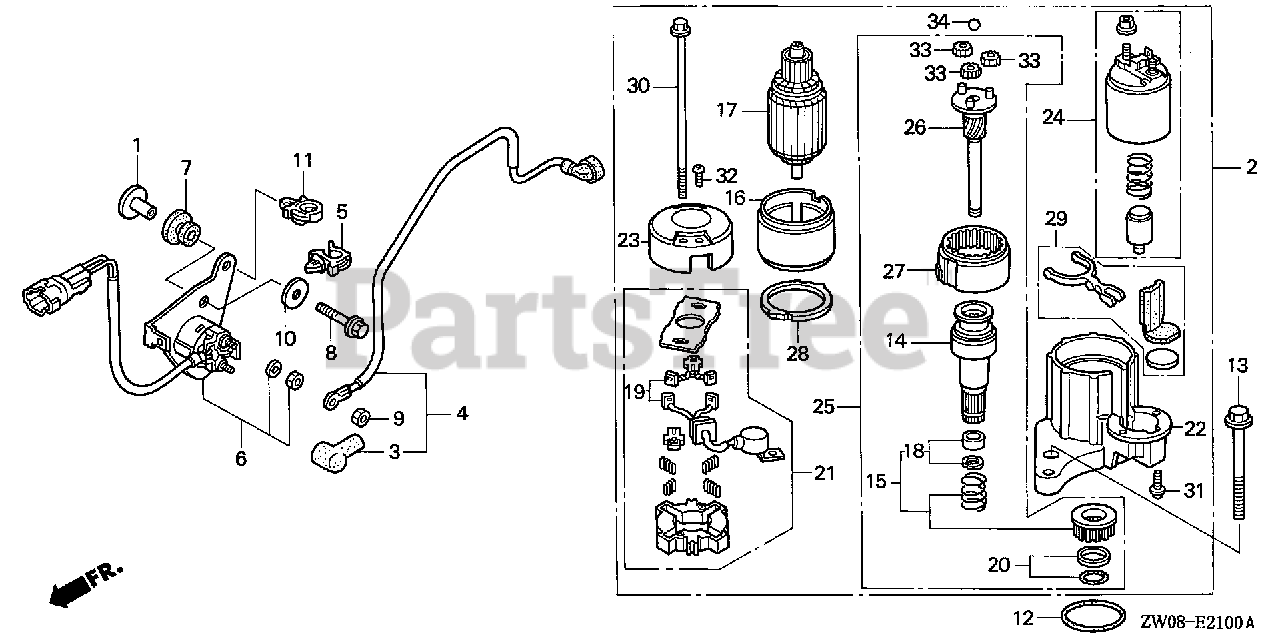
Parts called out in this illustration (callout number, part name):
1	COLLAR, FUEL TANK MOUNTING
2	MOTOR ASSY., STARTER
3	COVER, TERMINAL
4	WIRE, MAGNETIC SWITCH
5	CLAMP, WIRE
6	SWITCH ASSY., STARTER MAGNETIC
7	RUBBER A, LICENSE BRACKET CUSHION
8	BOLT, FLANGE (6X25)
9	NUT, HEX. (6MM)
10	WASHER, PLAIN (6MM)
11	CLIP, WIRE HARNESS
12	O-RING (54.4X3.1)
13	BOLT, FLANGE (10X90)
14	CLUTCH, OVERRUNNING
15	GEAR SET, PINION
18	STOPPER SET, PINION
20	STOPPER SET, SLEEVE
21	HOLDER, BRUSH
22	BRACKET, FR.
23	BRACKET, RR.
24	SWITCH ASSY., MAGNET
25	SHAFT ASSY., CLUTCH
26	SHAFT ASSY., GEAR
27	GEAR ASSY. (INNER)
30	BOLT A, THROUGH
31	SCREW, PAN (6X22) (SPECIAL)
32	SCREW, PAN (5X8)
33	GEAR ASSY., PLANETARY
34	BALL, STEEL
